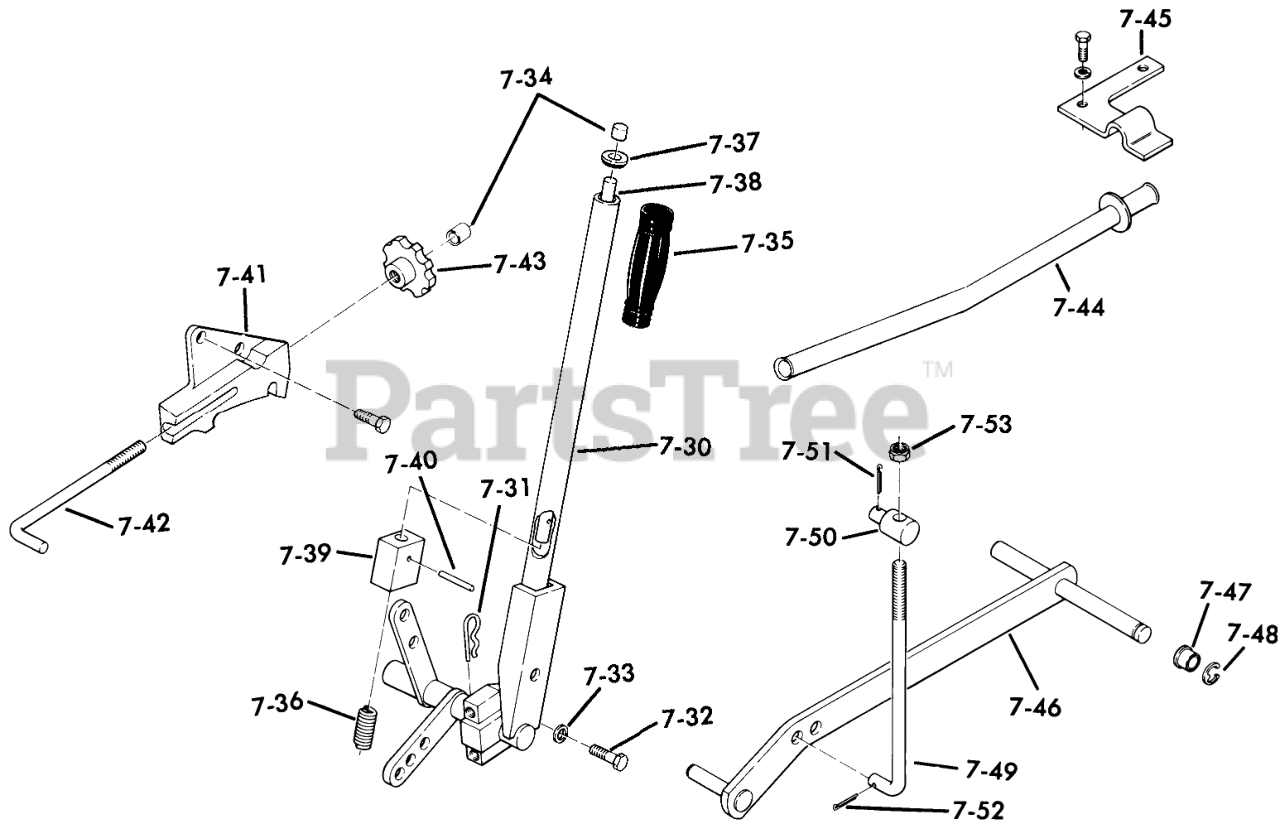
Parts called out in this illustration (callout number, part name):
7-30	Lift Lever
7-31	Hairpin
7-32	H H C S
7-33	Lockwasher
7-34	CAP-ROD, PLUNGER
7-35	HANDGRIP
7-36	SPRING-COMPRESSION
7-37	Guide-Rod
7-38	PLUNGER ROD
7-39	LOWER PLUNGER R
7-40	Roll Pin
7-41	Quadrant
7-41	Bolt
7-42	ROD-LIFT CONTROL
7-43	KNOB-LIFT CONTROL
7-44	TUBE ASSY COMPLET R
7-45	Clamp-Tube
7-45	Bolt
7-45	LOCKWASHER
7-46	ASSY LIFT BAR R
7-47	BUSHING
7-48	E Ring
7-49	ROD-LIFT
7-50	TRUNNION-LIFT
7-51	Hairpin
7-52	Cotter Pin
7-53	NUT
